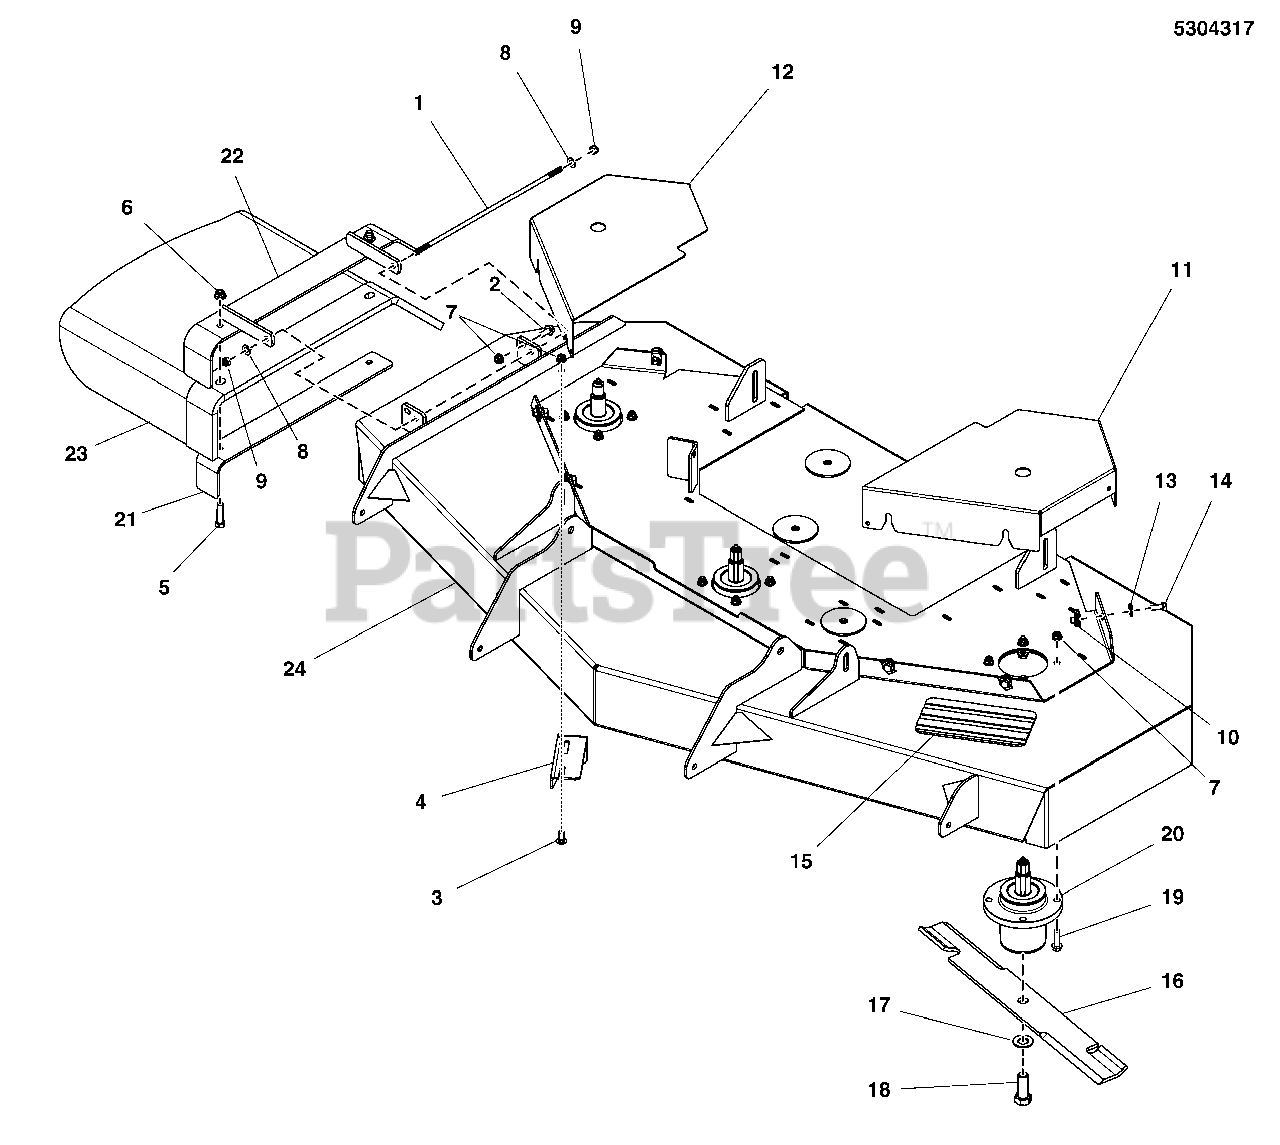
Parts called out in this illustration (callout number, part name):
1	ROD, 5/16 X 13.75, TBE, CZ
2	SCREW, 5/16-18
3	BOLT, 5/16-18 X 3/4, CARRIAGE
4	PLATE, DEFLECTOR - BLK
5	BOLT, 3/8-16 X 1-1/2, CARRIAGE, GD5, CZ
6	NUT, 3/8-16 HEX NYLOCK FLANGE
7	NUT, 5/16-18 HEX NYLOCK FLANGE
8	WASHER, 5/16 SAE
9	NUT, 5/16-24 HEX NYLON LOCK
10	BODY CLIP, 5/16-18-7GA MATERIAL
11	GUARD 61" - LH - RED
12	GUARD 61" - RH - RED
13	WASHER, 5/16 SAE
14	BOLT, 5/16-18 X 3/4 GD5
15	SAFETY WALK, 4.00 X 7.50
16	BLADE SET, .187 X 2.50 X 21.00 (3) (SV)
16	BLADE, .187 X 2.50 X 21.00
17	WASHER, 5/8 GRADE 8, YZ
18	BOLT, 5/8-11 X 1-3/4 GD8
19	BOLT, 5/16-18 X 1 1/4 FLANGE
20	ASSM, SPINDLE, LOW PROFILE
21	SUPPORT, DISCHARGE CHUTE - BLK
22	WELD, MOUNT, DISCHARGE CHUTE - BLK
23	CHUTE, RUBBER DISCHARGE - BLK
24	DECK SHELL W/DECALS,61,CNTDR,5414328C
